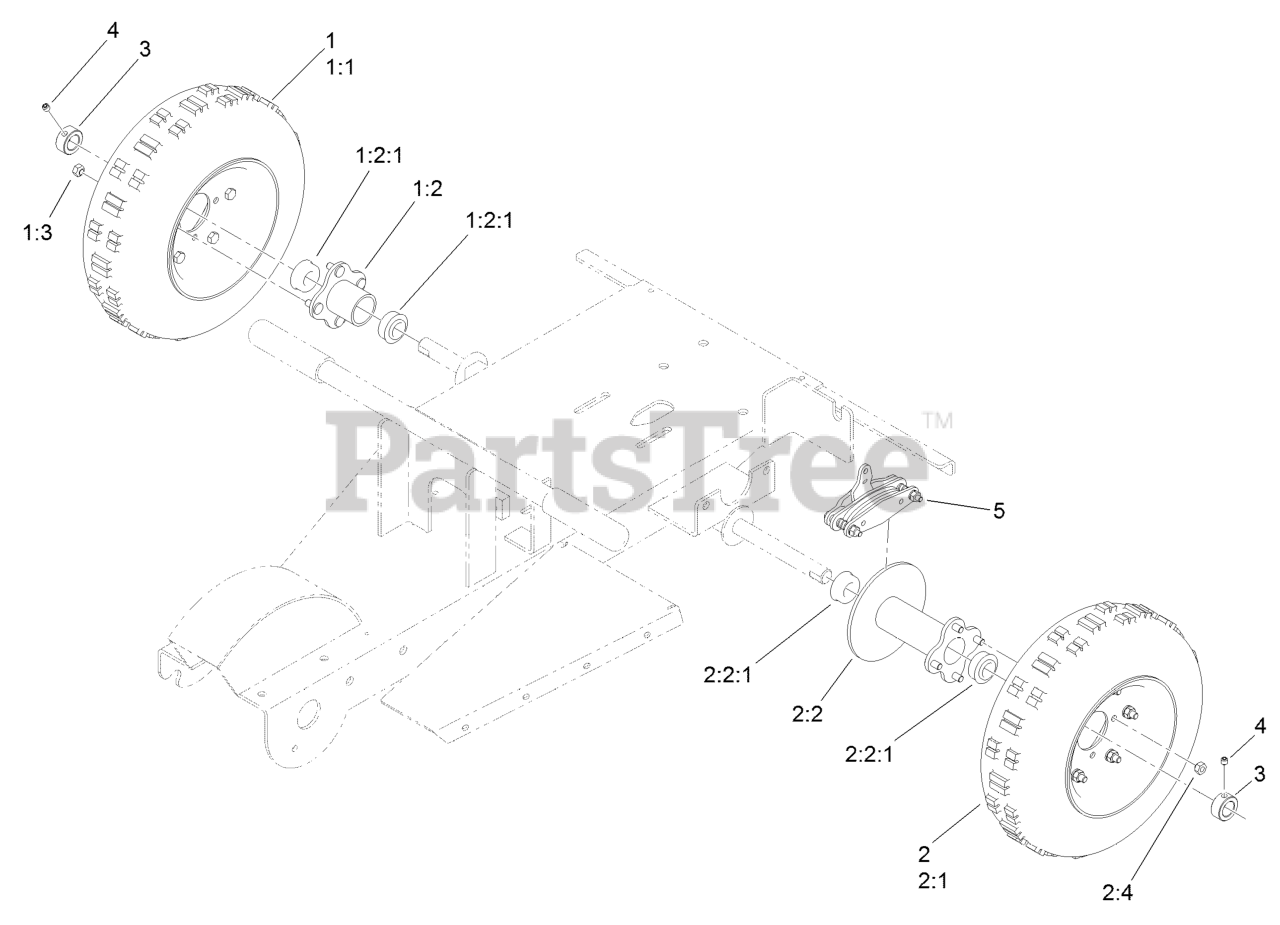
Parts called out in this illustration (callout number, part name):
1	TIRE ASM (W/ HUB)
1:1	Tire Asm
1:2:1	BEARING-WHEEL
1:3	NUT-WHEEL
2	TIRE ASM (W/ HUB AND BRAK
2:1	Tire Asm
2:2:1	BEARING-WHEEL
2:4	NUT-WHEEL
3	COLLAR-SET
4	SCREW-SET, HSH
5	BRAKE-CALIPER
